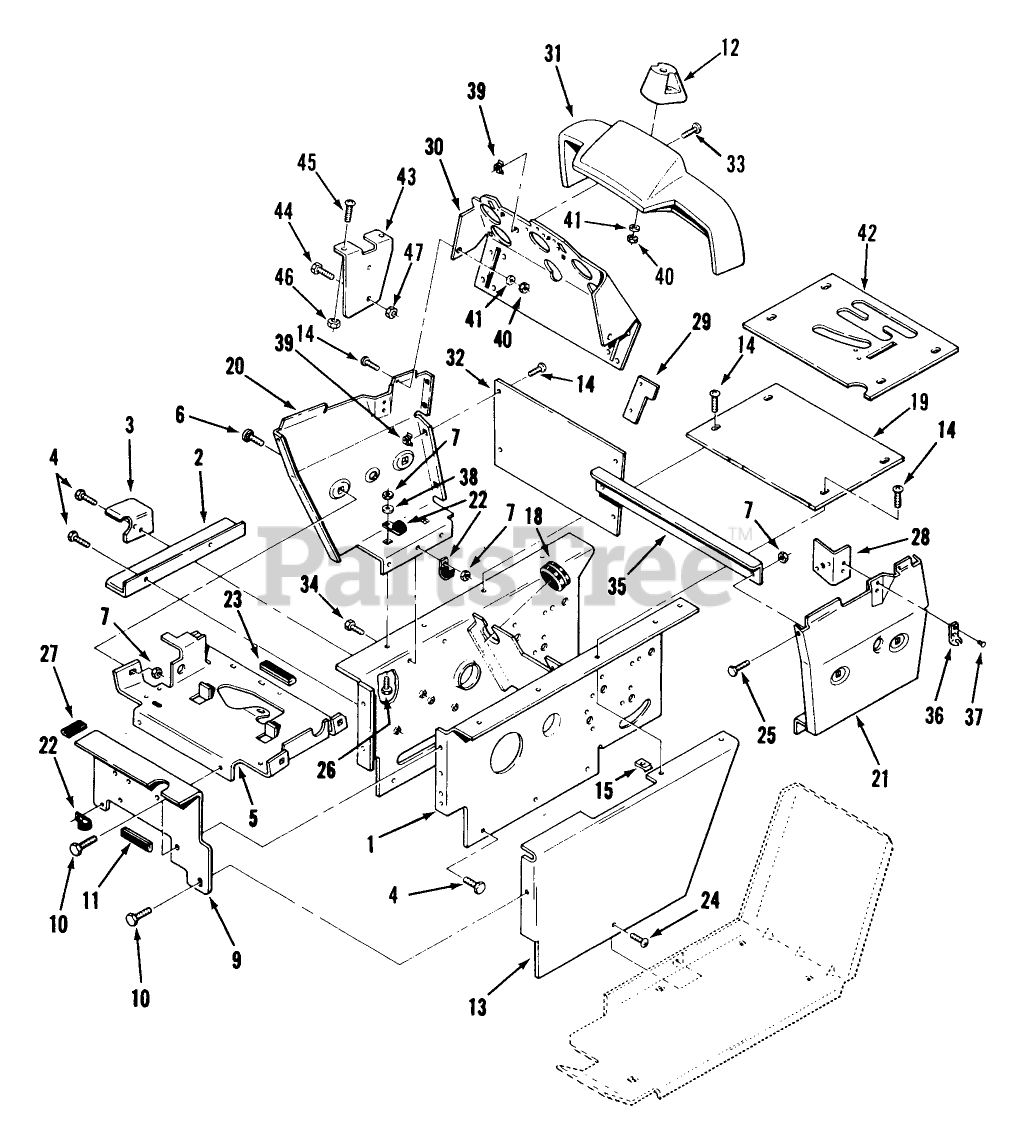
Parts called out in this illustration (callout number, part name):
2	ANGLE-BELT GUARD *B
4	SCREW
5	WLD-SUPPORT*B
10	SCREW
12	COVER-STEERING SHAFT
13	COVER-L.H. *R
14	SCREW-PPH
18	GROMMET
22	CLIP
26	CARRIAGE BOLT -4
28	BRACKET-SWITCH SU
29	STOP-CHOKE
30	Dash Panel
35	STIFFENER-PANEL
36	KEEPER-LATCH
37	RIVET
38	WASHER 5/16 SAE
